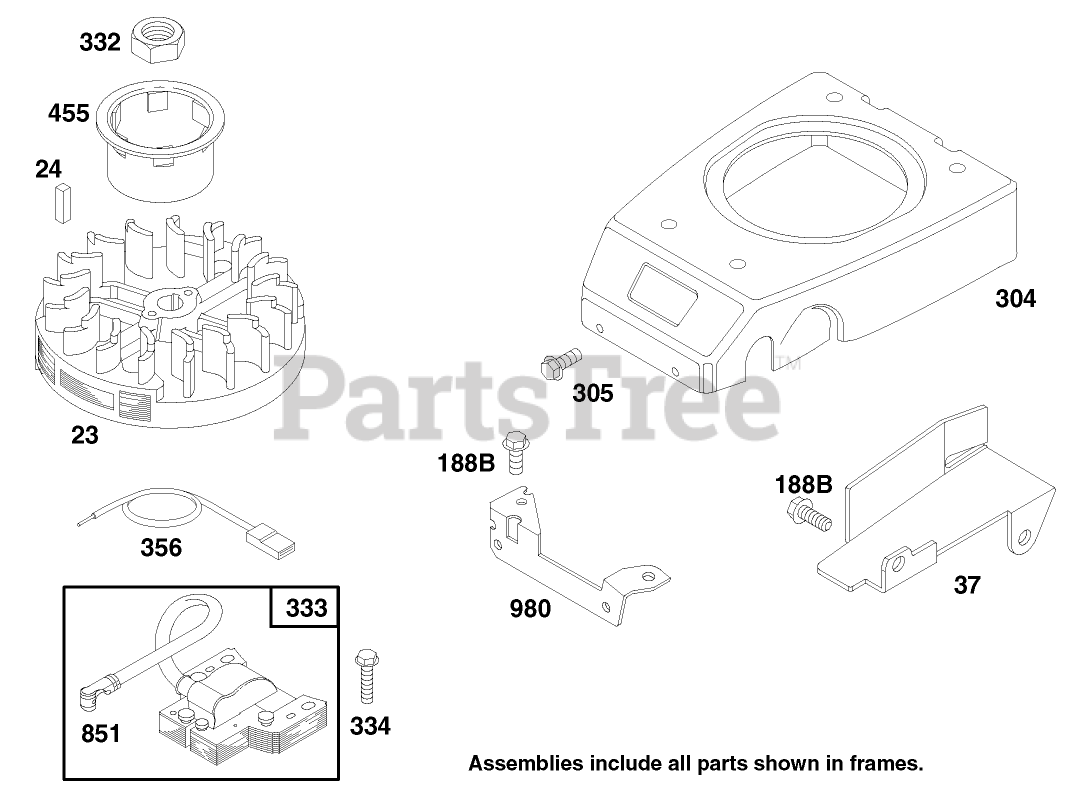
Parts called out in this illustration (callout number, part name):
24	KEY - FLYWHEEL
37	GUARD - FLYWHEEL
188B	SCREW - SEM
305	SCREW - HEX HEAD
332	NUT - HEXAGON
356	WIRE - GROUND
455	CUP - STARTER
980	BRACKET-BLOWER HSG
